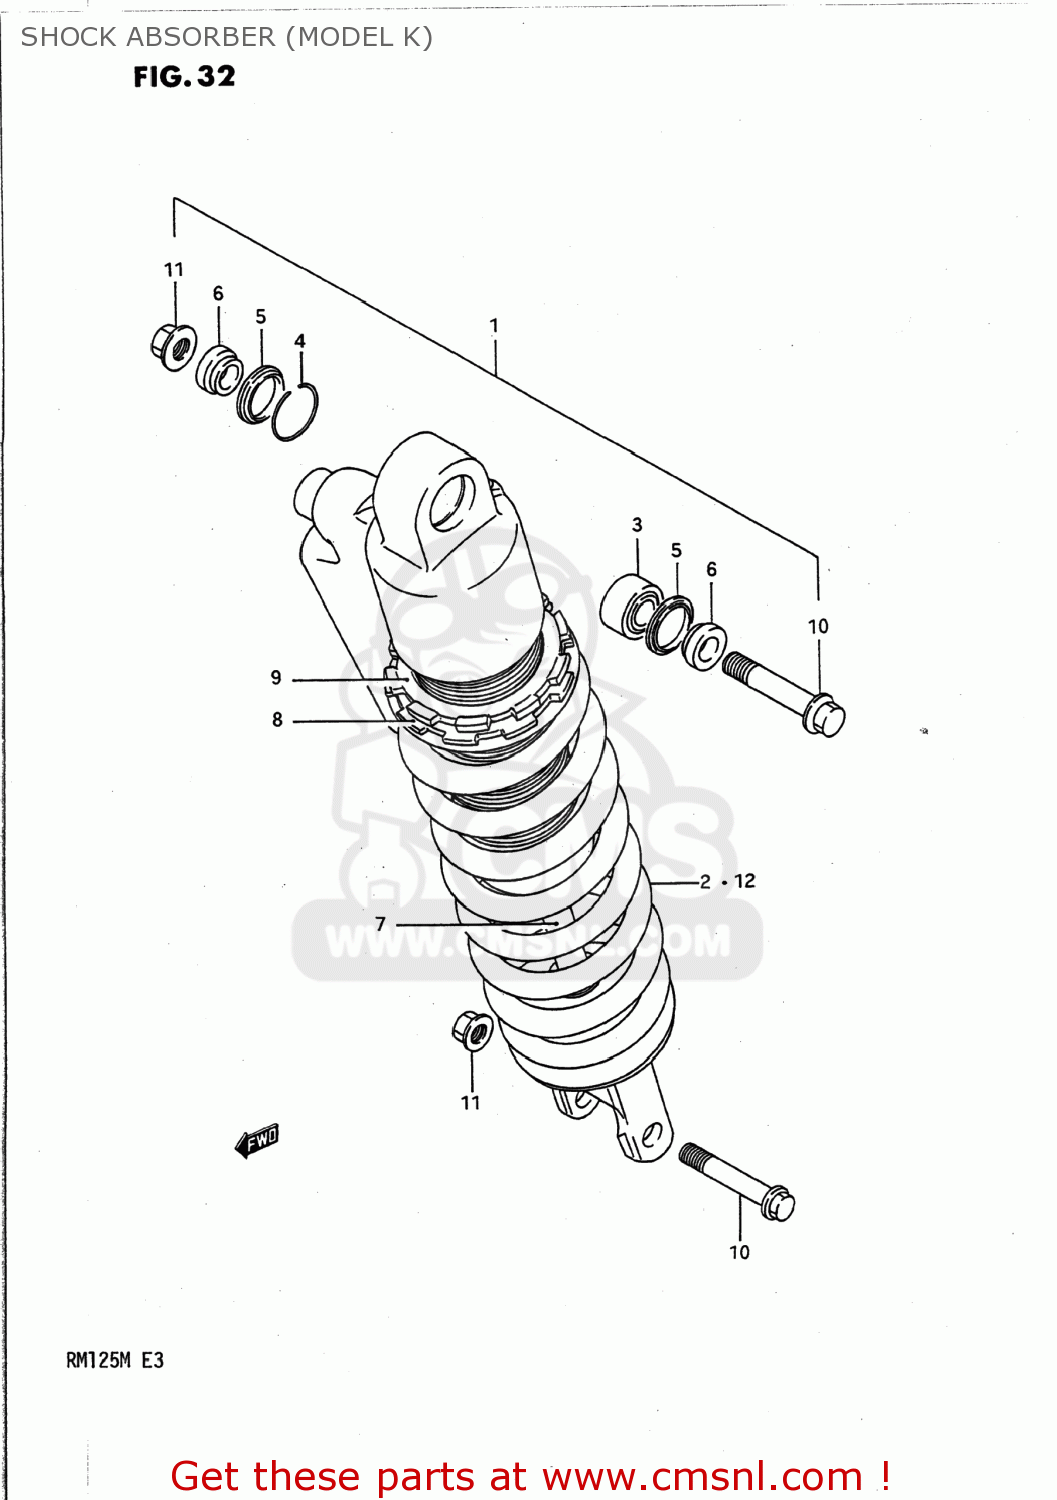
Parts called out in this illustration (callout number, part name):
1	ABSORBER ASSEMBLY,REAR SHOCK
2	SPRING
3	BEARING,RR CUSHION LEVER
4	RING
5	DUST SEAL
6	COLLAR
7	ROD,PISTON
8	GUIDE,SPRING
9	NUT
10	BOLT,REAR SHOCK ABSORBER
11	NUT
12	SPRING
